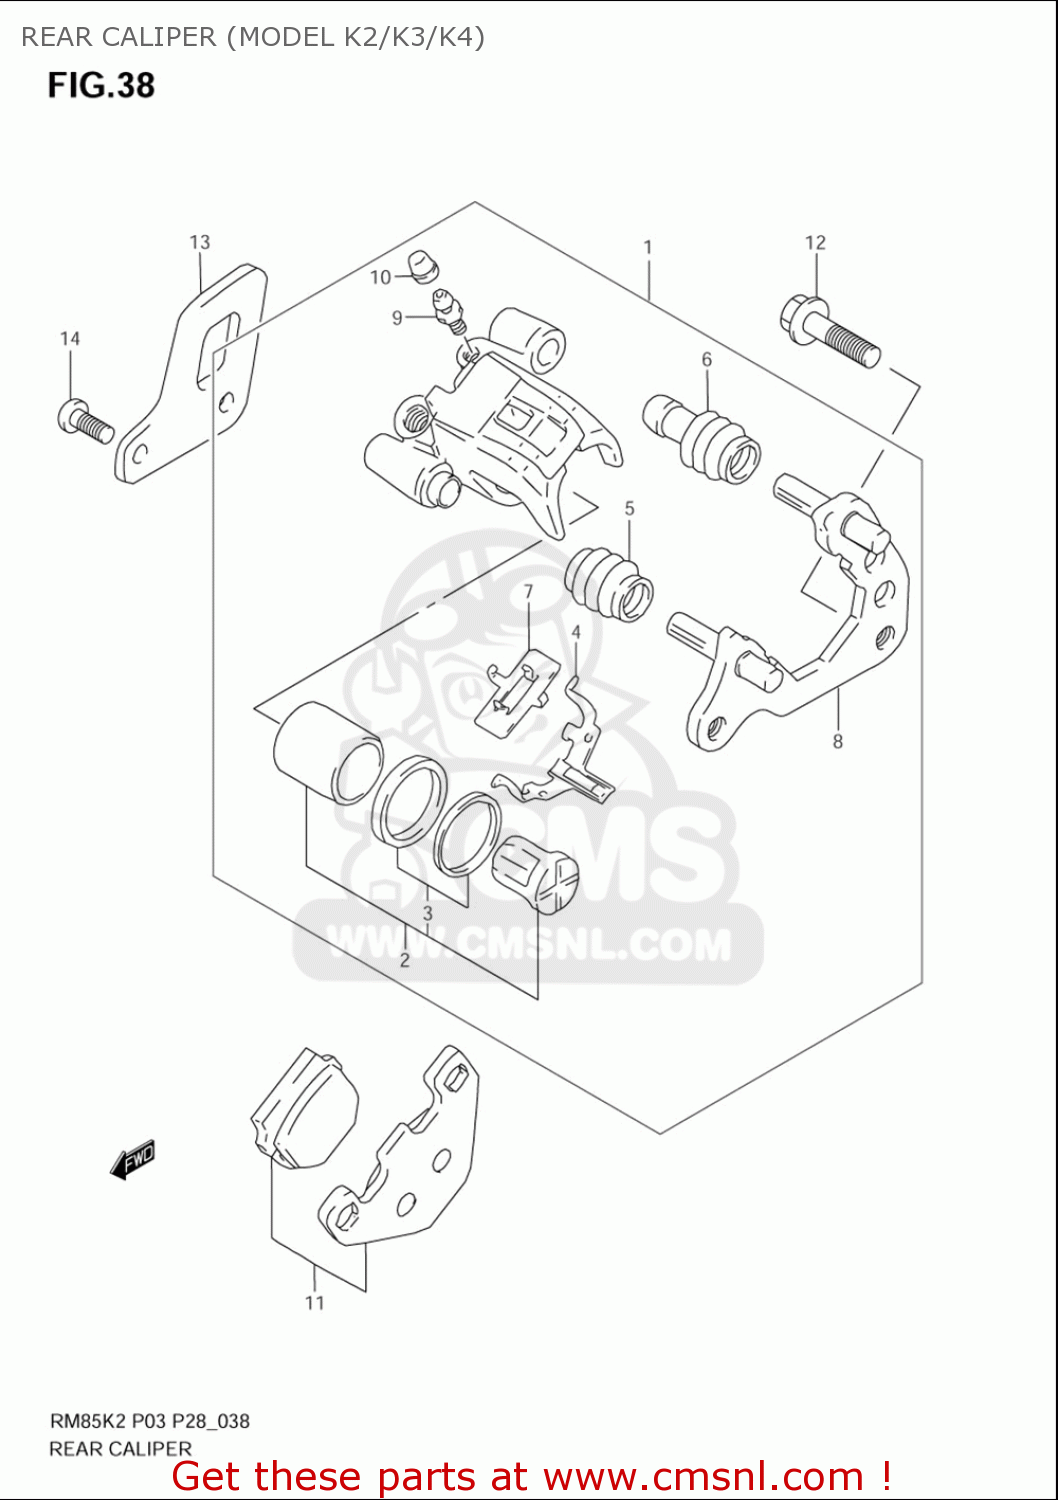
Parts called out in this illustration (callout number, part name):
1	CALIPER ASSY,RR
2	PISTON SET
3	SEAL SET,PISTON
4	SPRING,PAD
5	BOOT,AXLE
6	INSULATOR,AXLE
7	SHIM
8	CARRIER,CALIPER
9	BLEEDER
10	CAP,BLEEDER PLUG
11	PAD SET (NAS)
12	BOLT(8X18)
13	GUARD,RR CALIPER
14	SCREW(6X12)
